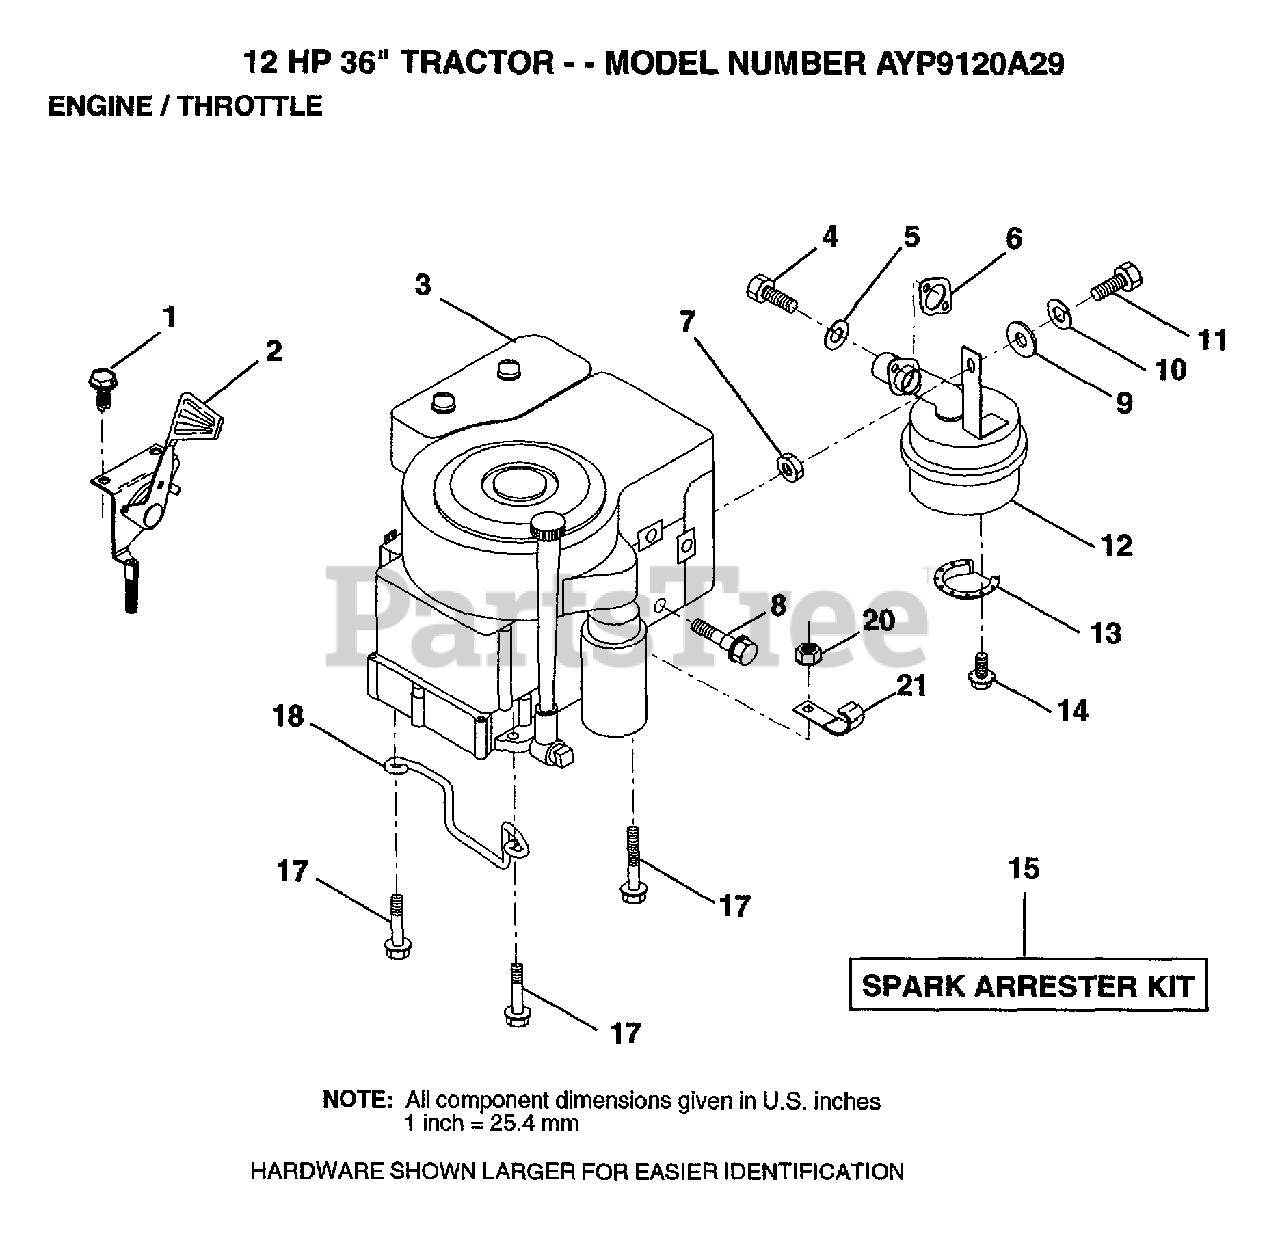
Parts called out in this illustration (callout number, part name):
1	SCREW
2	THROTTLE CONTROL
4	SCREW
5	LOCKWASHER
7	NUT.HEX.5/16-18
8	SHOULDER BOLT ST
10	LOCKWASHER
12	MUFFLER
13	DEFLECTOR.222573
17	SCREW LT
18	"KEEPER,DR BELT GR"
20	NUT
21	CLIP T
